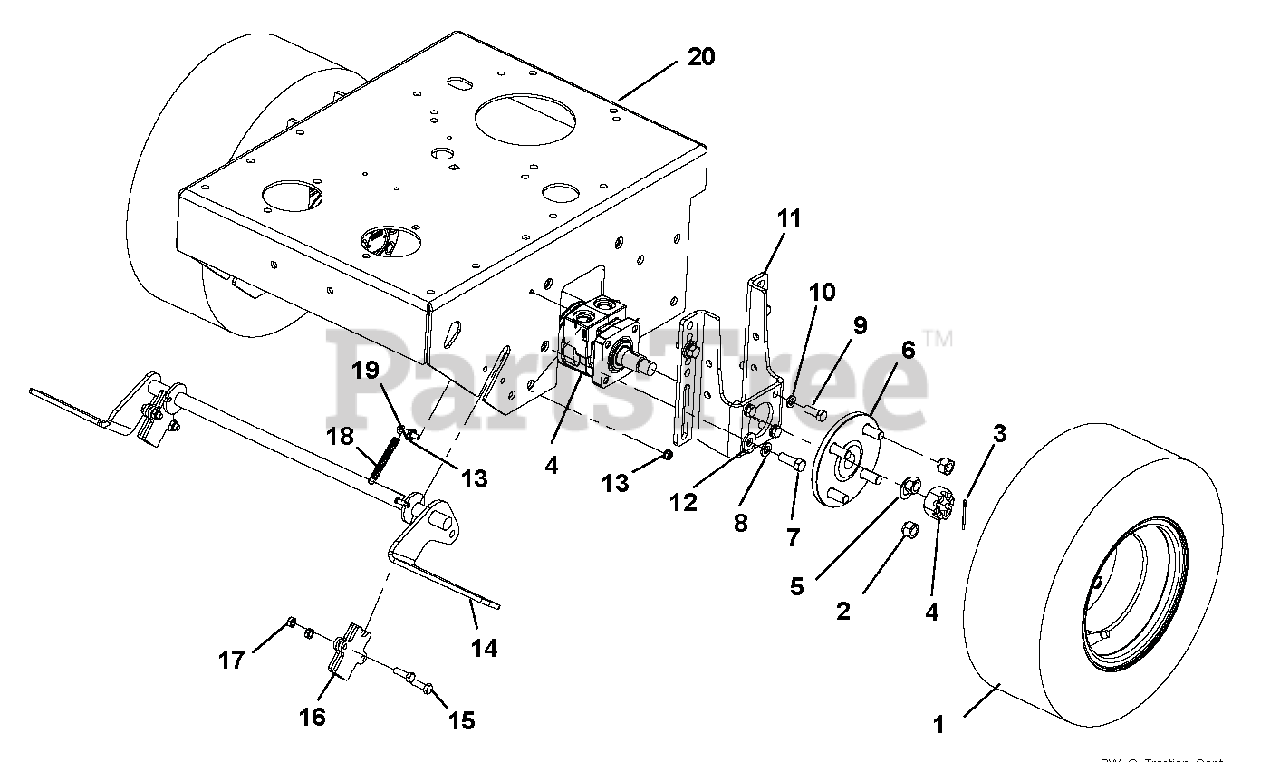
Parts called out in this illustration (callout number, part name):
1	ASSY, WHEEL & TIRE - 16X6.5-8
2	NUT, 1/2-20 LUG C
3	PIN, COT .125X1.50 EXTP Y
4	MOTOR, HYDRAULIC WHEEL
5	BUSHING, MACH .750X1.25X.048 Y
6	ASSY, WHEEL HUB
7	BLT-HEX .44-14X1.25 GR5 YWZC
8	WASHER, .438 MED SPRG LOCK Y
9	BOLT, 3/8-16 X 1 GR8 BLACK
10	WASHER, .375 MED SPRG LOCK Y
11	BRACKET, MOTOR MOUNT S/O
11	BRACKET, MOTOR MOUNT WIDETRAC
12	WASHER, .468X1.00X.125 FLAT Y
13	LOCKNUT, 1/4-20 WHIZ Y
14	WLDT, BRAKE SYS 36" FLWLK
14	WLDT, BRAKE SYSTEM 48/52 FXWLK
15	BLT-HEX .31-18X1.00 GR5 YWZC
16	SHOE, BRAKE SYSTEM SCAMPER
17	LOCKNUT, 5/16-18 NYLOC Y
18	SPRING, EXT .375X.055X2.25 Y
19	BLT-HEX .25-20X1.25 GR5 YWZC
20	WLDT, 18" ENG BED FX SCAMPER
